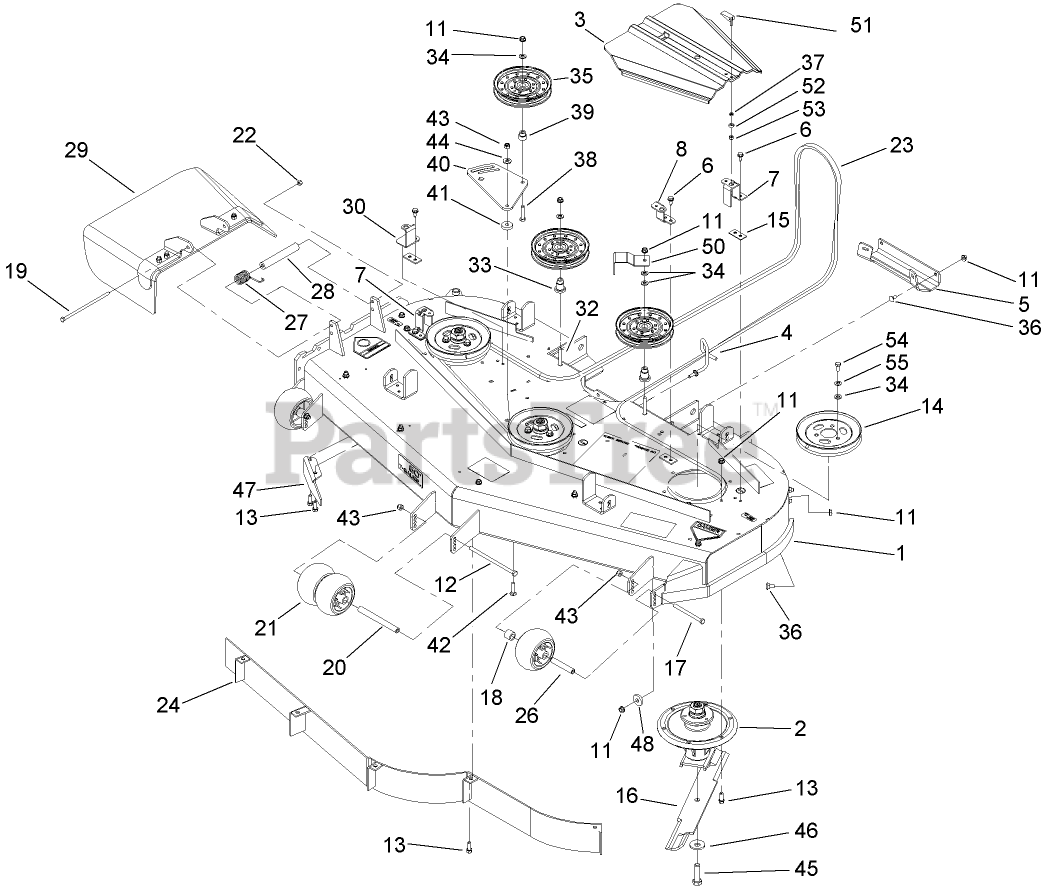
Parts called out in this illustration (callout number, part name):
1	DECK DECAL ASM
2	SPINDLE ASM
3	COVER-BELT
4	GUIDE-BELT
5	Plate-Skid
6	SCREW-HWHTF
7	BRACKET-COVER
8	BRACKET-COVER, TALL
11	NUT-HHF, WHIZ
12	SCREW-HH
13	SCREW-HWH
14	Pulley
15	SPACER-COVER, BELT
16	BLADE-HI FLOW
17	SCREW-HH
18	TUBE-SPACER
19	SCREW-HH
20	SPACER-WHEEL
21	ROLLER-SCALP, ANTI
22	NUT-LOCK, NI
24	BAFFLE ASM
26	TUBE-SPANNER
27	SPRING-TORSION
28	SPACER
29	RUBBER DEFLECTOR ASM
30	BRACKET-COVER
32	SCREW-CARR
33	MOUNT-PULLEY
34	WASHER-FLAT
35	Idler-Flat
36	SCREW-CARR
37	WASHER
38	SCREW-HH
39	BUSHING-IDLER
40	Plate-Idler
41	Spacer
42	SCREW-CARR
43	NUT-LOCK, NI
44	WASHER-BELLEVILLE
45	SCREW-BLADE
46	Washer-Blade Bolt, Heavy
47	BAFFLE-DISCHARGE
48	WASHER
50	GUIDE-BELT
51	HANDLE-LATCH, SWELL
52	BUSHING-LATCH, SWELL
53	NUT-LOCK, HH
54	SCREW-HH
55	WASHER-BELLEVILLE
